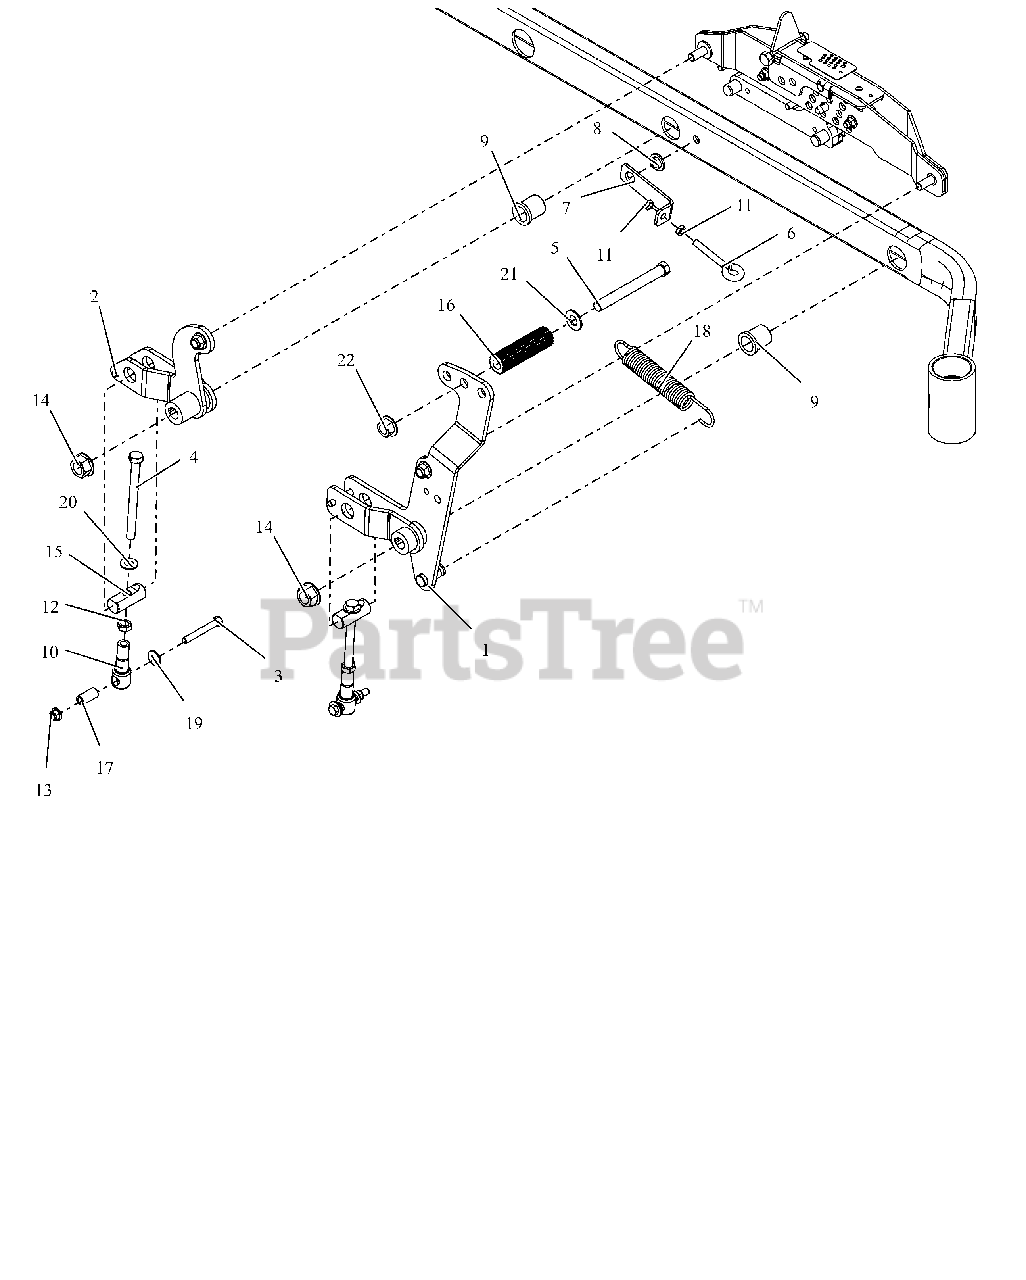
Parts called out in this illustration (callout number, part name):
1	FRT RH DECK LIFT ARM WMT- LF
2	REAR RH DECK LIFT ARM WMT- LF
3	BLT, HEX .38-16X2.75 G8 ZCC
4	BLT, HEX .50-13X6.00S G5 ZCC
5	BLT, HEX .62-11X5.50 G5 FBP
6	BLT-EYE .375-16X2.50 YWZC
7	SPRING ANCHOR BRACKET - RED
8	BSHG-FLG .515X.750X.310X1.120
9	BSHG-FLG 1.00X1.25X1.50X1.50
10	LINK, DECK LIFT FORMED
11	NUT-JAM .375-16 G2 ZCC
12	NUT-JAM .500-13 G2 ZCC
13	NUT,NYL-FLG .38-16 GF ZCC
14	NUT,FLG-TOP LK .625-11 FBP
15	PIN, DECK LIFT
16	ROD, FOOT PEDAL (BLACK)
17	SPACER, DECK LEVELING
18	SG-TENS .162X1.25X8.25 WLD 25
19	WSHR,FLT .438X1.00X.083 ZCC
20	WSHR, FLT .557X1.040X.102 ZCC
21	WSHRFLT 5/8SAE CARBHARD FBP
22	NUT,FLG-TOP LK .625-11 FBP
